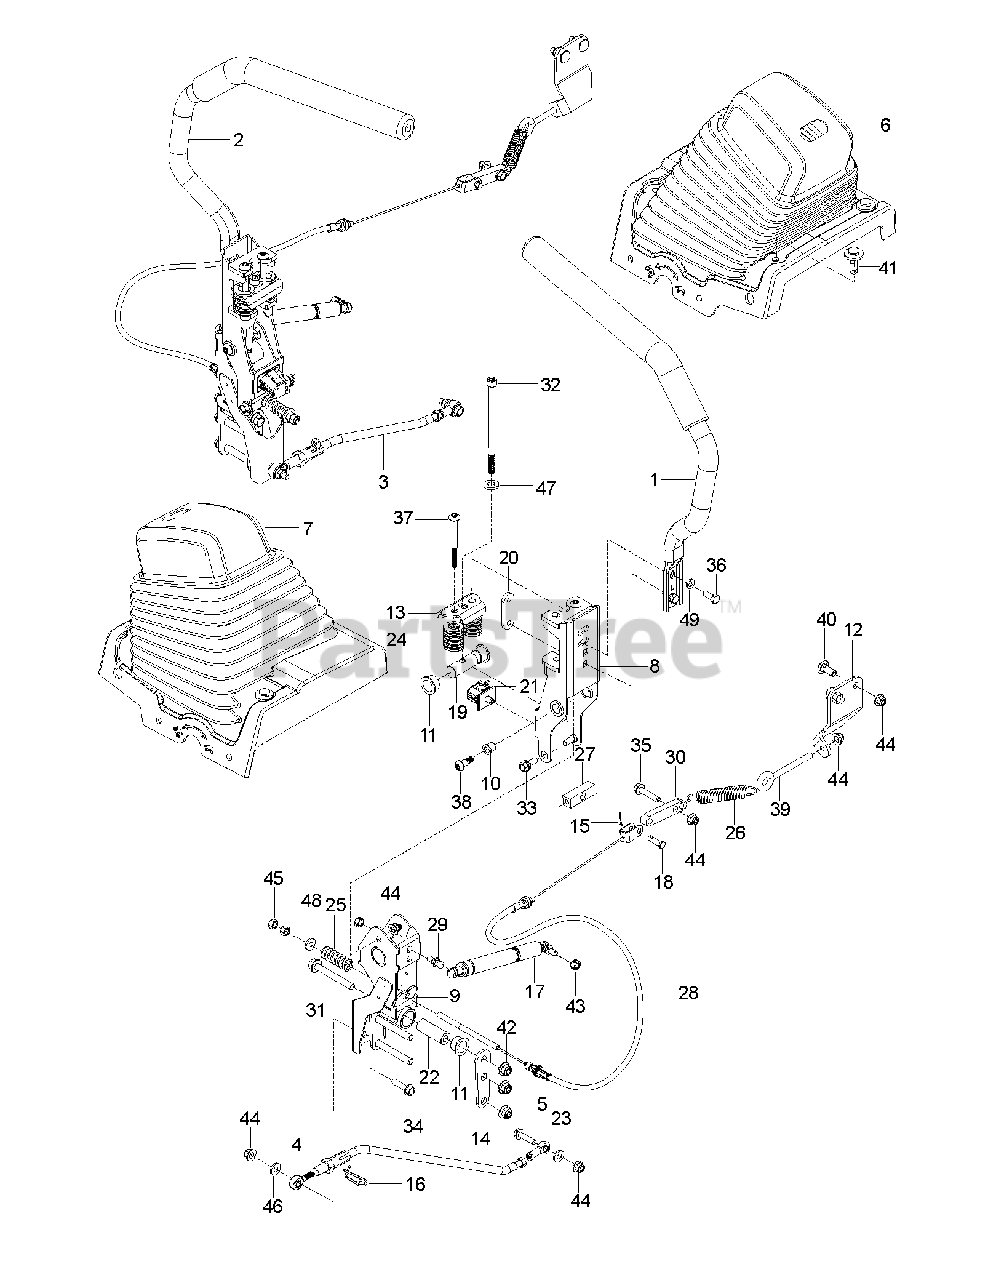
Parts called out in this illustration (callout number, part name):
1	Drive Lever Assembly, LH
2	Drive Lever Assembly, RH
3	ROD.ASM.CONTROL.PZ.5400.LH
3	ROD.ASM.CONTROL.PZ.5400.RH
4	ROD.END.MALE.LH.THREAD
5	Joint Heim, Feml.516.R
6	KIT.SERVICE.LEVER.BELLOW.LH
7	KIT.SERVICE.LEVER.BELLOW.RH
8	CARRIER.PNT.WELD.UPPER.LH.EDIP
8	CARRIER.PNT.WELD.UPPER.RH.EDIP
9	CARRIER.PNT.WLDMT.LOWER.EDIP
10	BEARING.FLG.3/8.SHAFT.1/2.HSG
11	BEARING, FLANGE
12	BRACKET.PNT.RETRN.SPRNG.LH.BLK
12	BRACKET.PNT.RETRN.SPRNG.RH.BLK
13	BRACKET.RETAINING.SPRING
14	BRACKET.PNT.CONTROLS.MTG.EDIP
15	RETAINER CLIP
16	CLIP.RETAINER.CONTROLS
18	PIN.CLEVIS.5/16.DIA.3/4.USABLE
21	SWITCH.SNPMNT.DELTA.NCNC.PZREF
22	SPACER.PIVOT
23	SPACER.7_16OD;5_16ID;STEP.UP
24	SPRING 1.25"ODX1.5"L
25	SPRING, BRAKE ROD
26	SPRING.RETURN.BRAKE
27	CABLE.YOKE.PARK.BRAKE
28	Parking Brake Cable
29	STUD.BALL.10MM
30	BRACKET.EXTENSION
31	HHFS 3/8-16 X 3 GRD 5 ZD
32	SCREW.SHCS.3/8-16 X 6L.ZY
33	BOLT, SHOULDER
34	HHFS 5/16-18 X 1.25 TPBLT GD 5
35	HHFS 5/16-18 X 1.5 GD 5
36	HCS 5/16C X 3/4
37	SCREW.SHCS.5/16-18 X 3-1/2"
38	SCREW.SHLDR.3/8 X 1/2.5/16-18
39	EYE BOLT 5/16 X 3.50
40	RHSNB 5/16C X 1
41	RIVET.PUSH.PIN.0.25IN.HOLE
42	NUT 3/8-16 HEX FLG NYLOC ZD
43	NUT 5/16C CENTERLOCK
44	5/16-18 NYLOC FLANGE NUT
46	WASHER
47	WASHER, 3/8 THICK
48	WASHER 5/16 FLAT
49	WASHER 5/16 LOCK
